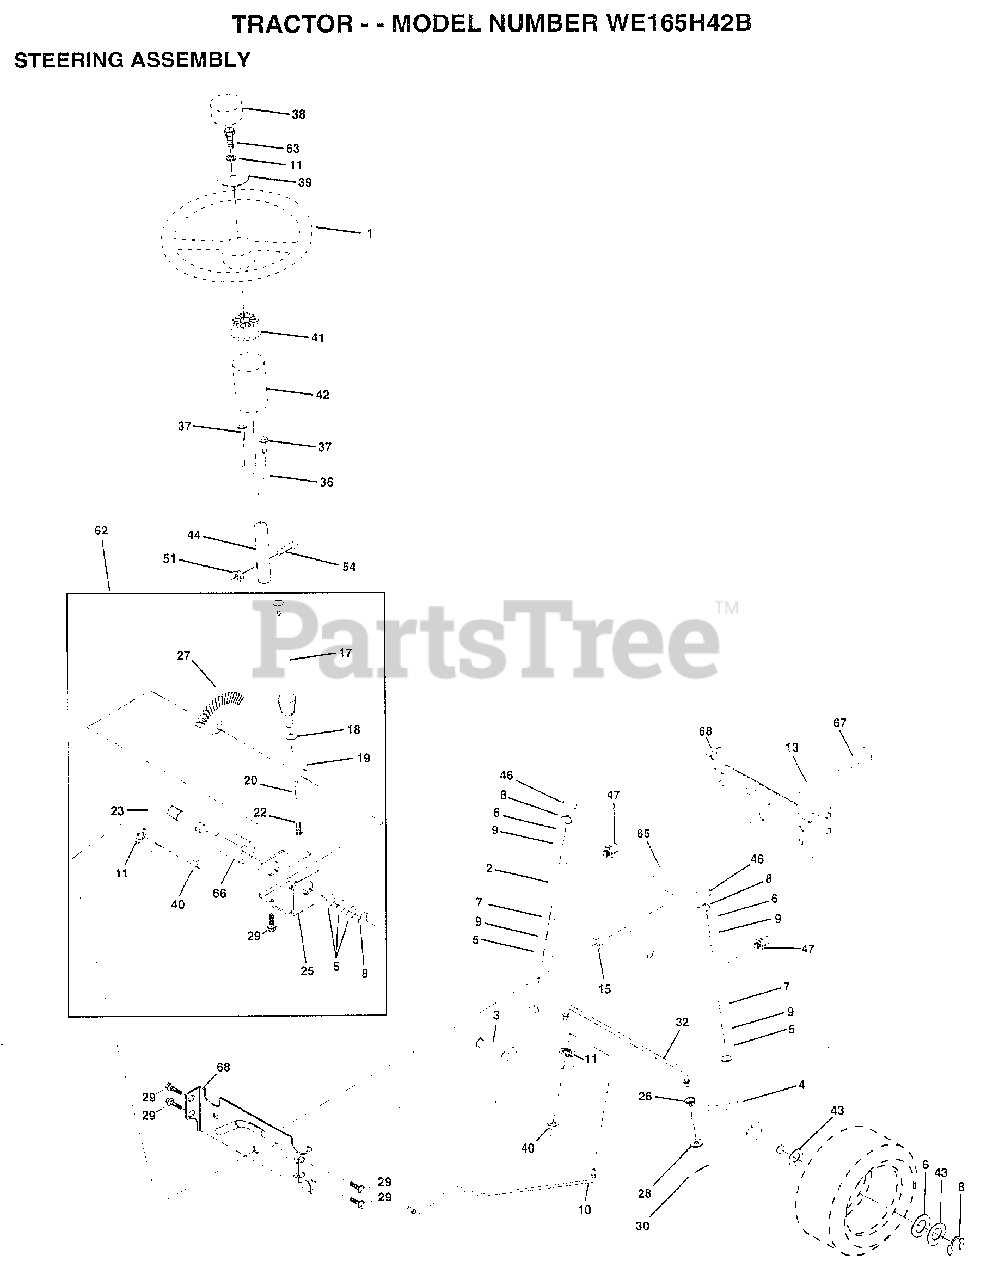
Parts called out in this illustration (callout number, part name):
1	WHEEL STR AYP BLK
2	AXLE ASM
3	SPINDLE.ASM.LH
4	"SPINDLE ASM,RH"
5	WASHER .T
6	WASHER
7	WASHER
8	RING
9	COL. SRTG. BEAR.
10	DRAGLINK-STAMPED
11	LOCKWASHER
13	BEARING AXLE
15	"NUT-LOC,FLANGE LT"
17	SHAFT ASM STEERIN
18	THRUST WASHER
19	SUPPORT.SHAFT
22	SCREW HEX SOC1/4-
25	BRKT-STEERING
26	BUSHING.DRAGLINK
27	GEAR SECTOR
28	WASHER
29	SCREW
30	COTTER PIN
32	TIE ROD
36	BUSHING.STEERING
37	"SCREW-TT,10-32 FL"
38	CAP STEER AYP
39	WASHER T
40	GRIPCO NUT
41	ADAPTER LT
42	BOOT.STEER.PL
44	EXT SHAFT STEERIN
46	CAP
47	ZERK M
51	NUT
54	BOLT
62	KIT STEERING ASM
63	BOLT
65	SPACER AXLE
66	"BEARING-ARM,PITMA"
67	BOLT
68	BRACE AXLE
